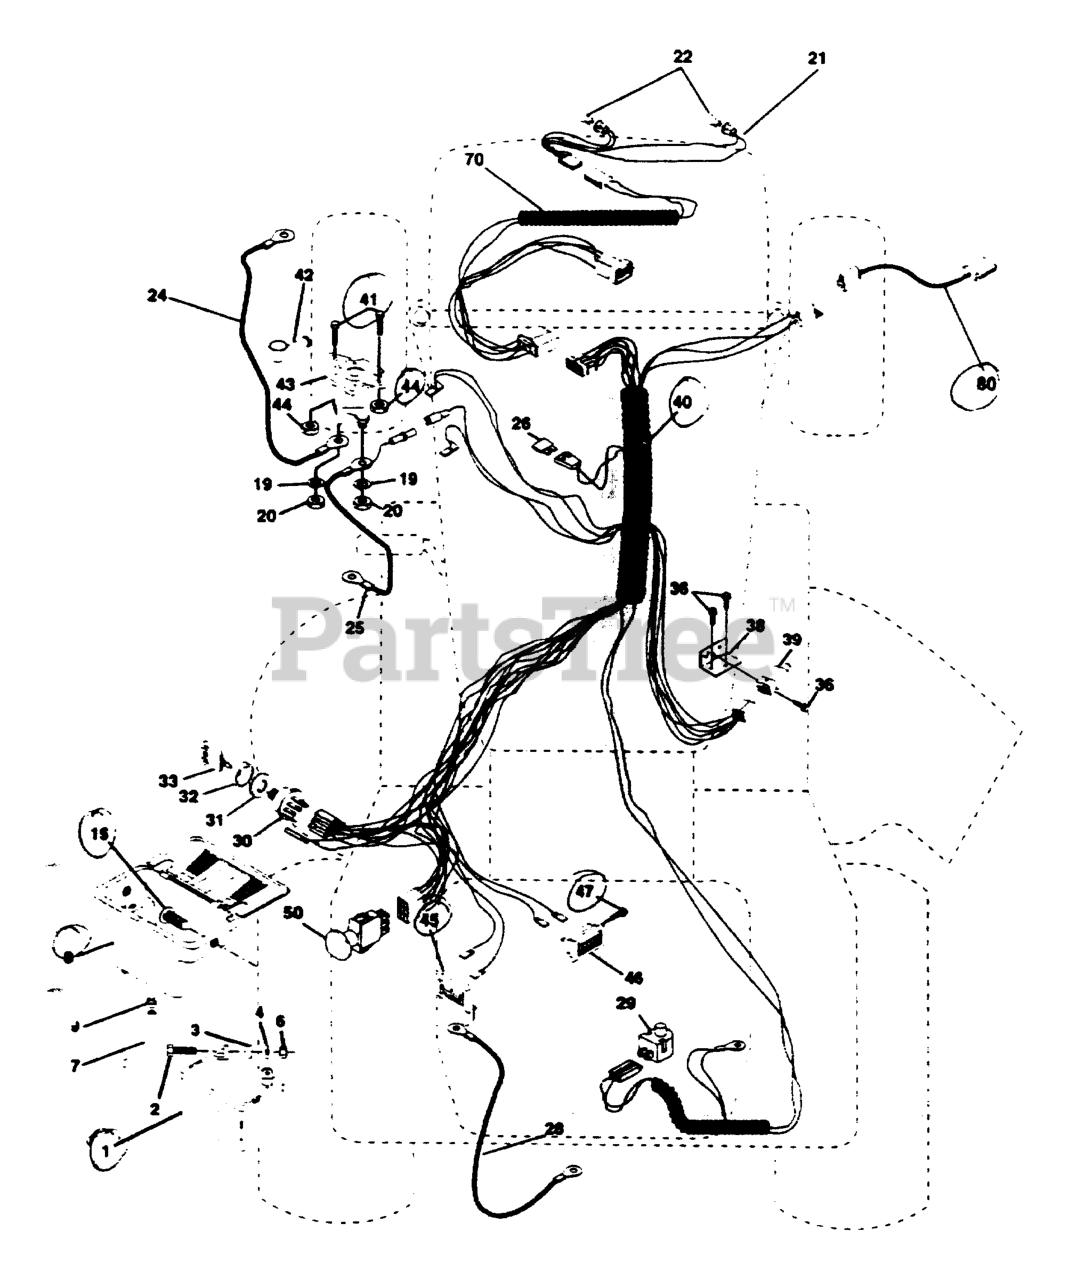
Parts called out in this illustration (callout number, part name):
1	BATTERY
2	BOLT.HEX.1/4.X.3/4.DICHROMATE
4	LOCKWASHER
6	NUT
7	TUBE BATTERY DRAIN
8	BATTERY CASE
9	HOSE CLAMP T
15	FASTERER SNAP-IN
19	LOCKWASHER
20	NUT
21	HARNESS LIGHT SOCKET
24	BATTERY CABLE GT
25	CABLE BATTERY
28	CABLE T
29	RP.SWITCH.PLUNGER.NC.GRAY
30	SWITCH.IGNITION.4.POSITION
31	NUT IGNITION
32	COVER SWITCH KEY
33	KEY.MOLDED.GENERIC
35	BRACKET LT
38	SWITCH BRACKET
39	SWITCH INTERLOCKT
40	HARNESS IGN ELEC P/L
41	BOLT
42	TERMINAL COVER
43	SOLINOID
44	NUT
45	AMMETER
46	HOUR METER T
50	SWITCH-PTO
70	HARNESS ENGINE
80	HARNESS, CLUTCH
